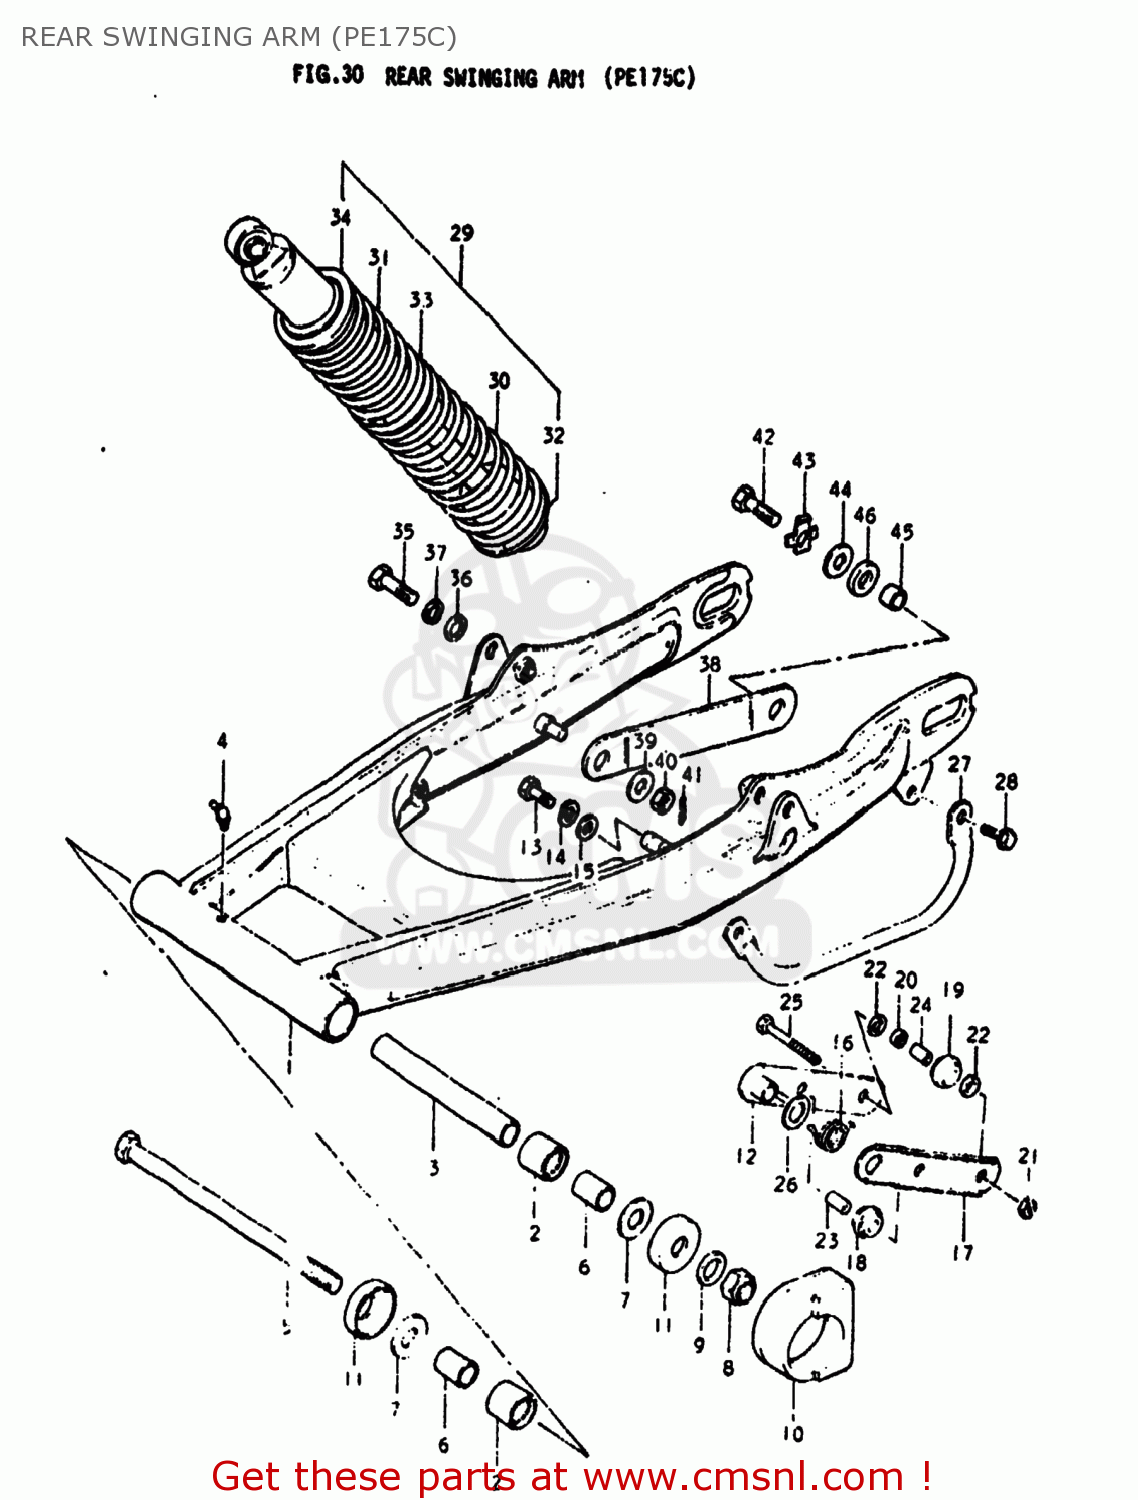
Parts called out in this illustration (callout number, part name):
1	SWING ARM ASSEMBLY,REAR
2	ROLLER BEARING (17X24X2
3	SPACER,REAR SWING ARM PIVOT
4	NIPPLE,GREASE
5	SHAFT,REAR SWING ARM
6	SPACER,RR SWGARM PIVOT
7	WASHER
8	NUT 12MM
9	WASHER
10	BUFFER,CHAIN TOUCH DEFENSE
11	COVER,RR SWGARM DUST SEAL
12	TENSIONER,CHAIN
13	BOLT
14	LOCK WASHER
15	WASHER
16	SPRING
17	PLATE,CHAIN TENSIONER OUTER
18	RUBBER,CHAIN GUARD
19	ROLLER,CHAIN TENSIONER LWR
20	BEARING(10X14X15)
21	NUT 6MM
22	SEAL,OIL(10X14.4X3.5)
23	SPACER(6.5X10.5X22.5)
24	SPACER(6.2X10X22.5)
25	BOLT
26	WASHER
27	GUARD
28	BOLT 8X12
29	ABSORBER ASSEMBLY,REAR SHOCK
30	SPRING
31	SPRING
33	SPRING
34	GUIDE,SPRING
35	BOLT 10X40
36	WASHER
37	LOCK WASHER
38	TORQUE LINK,REAR
39	WASHER (10.1X21X2.3)
40	NUT
41	PIN 20X20
42	BOLT
44	WASHER
45	SPACER
46	WASHER (14X25X3)
